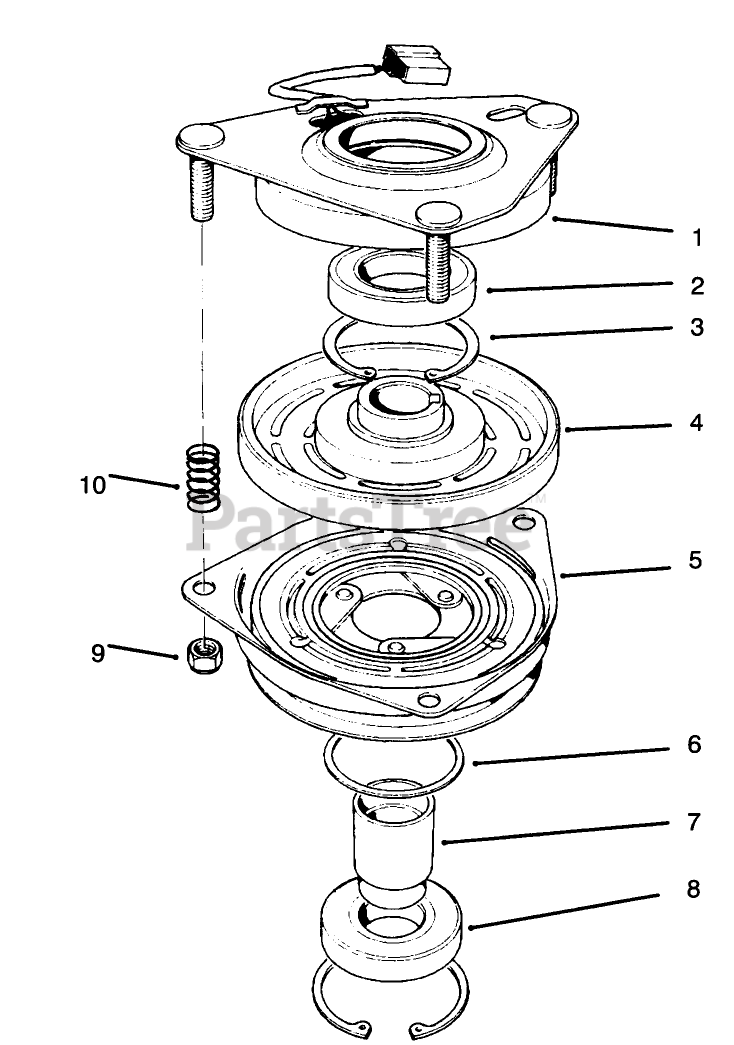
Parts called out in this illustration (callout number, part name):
1	FIELD BEARING ASM
2	BEARING-FIELD
3	RING-RETAINING
4	FIELD COIL/ROTOR BEARING ASM
6	SPACER-BEARING, PULLEY
7	COLLAR-BEARING
9	NUT-HEX
10	SPRING
